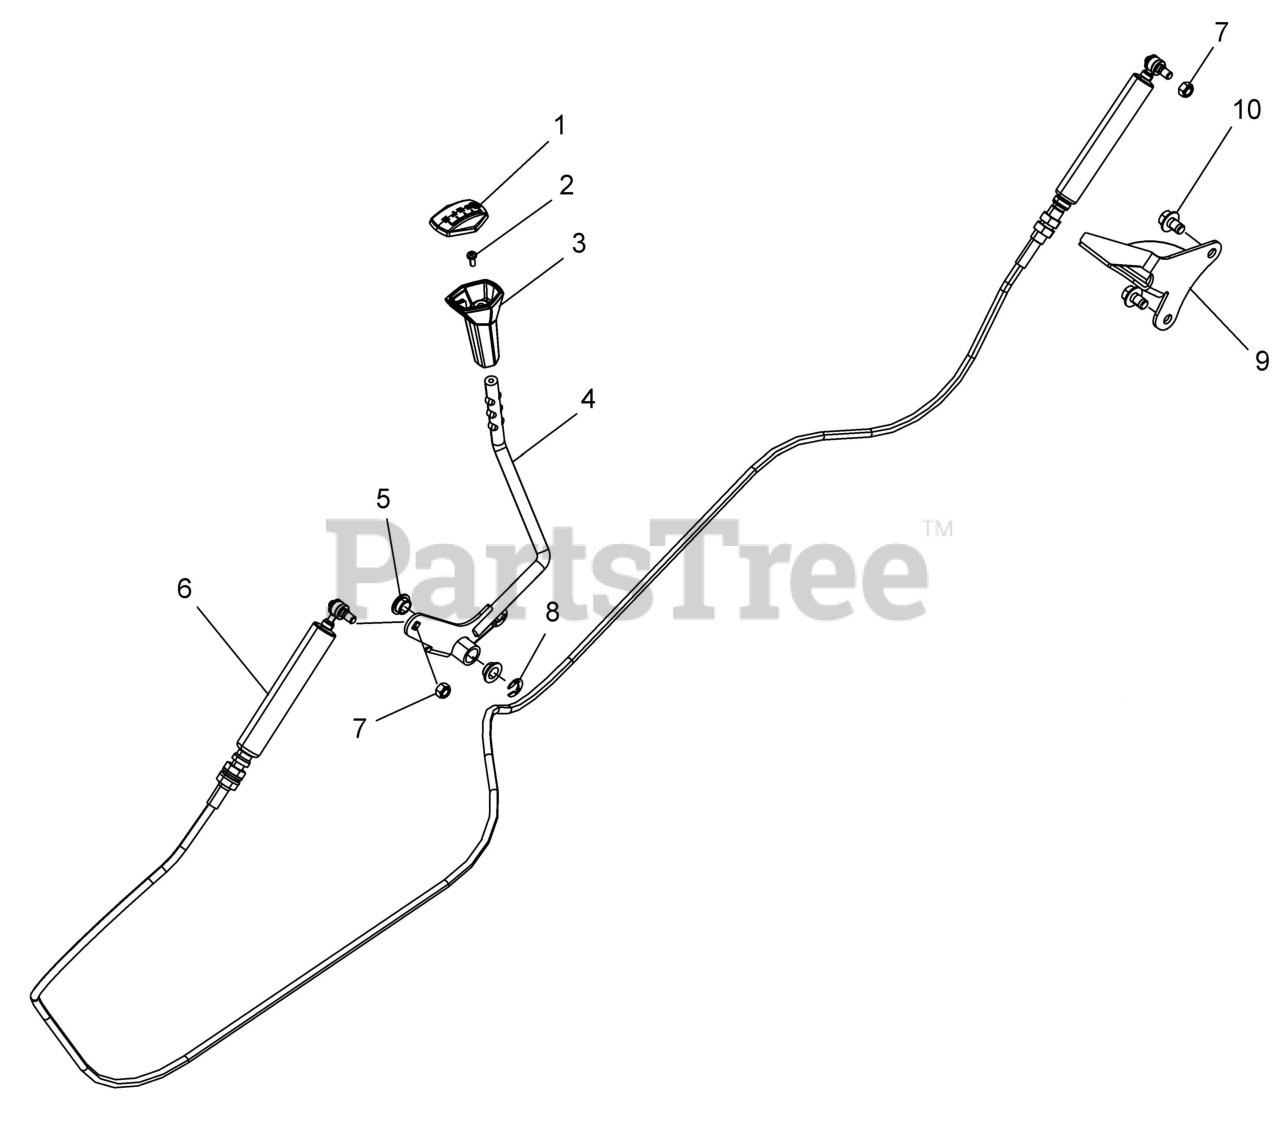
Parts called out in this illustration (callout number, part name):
1	COVER-SHIFT
3	KNOB-GEAR SELECTOR SHIFT
4	WELD-SHIFT LEVER,BLK
5	BUSHING-PEDAL PIVOT
6	CABLE, SHIFT
7	NUT,NYLOK M8X1.25(10) *
9	BRKT-SHIFT CABLE
10	BOLT-M10X1.25X16,HXHD,FLG
